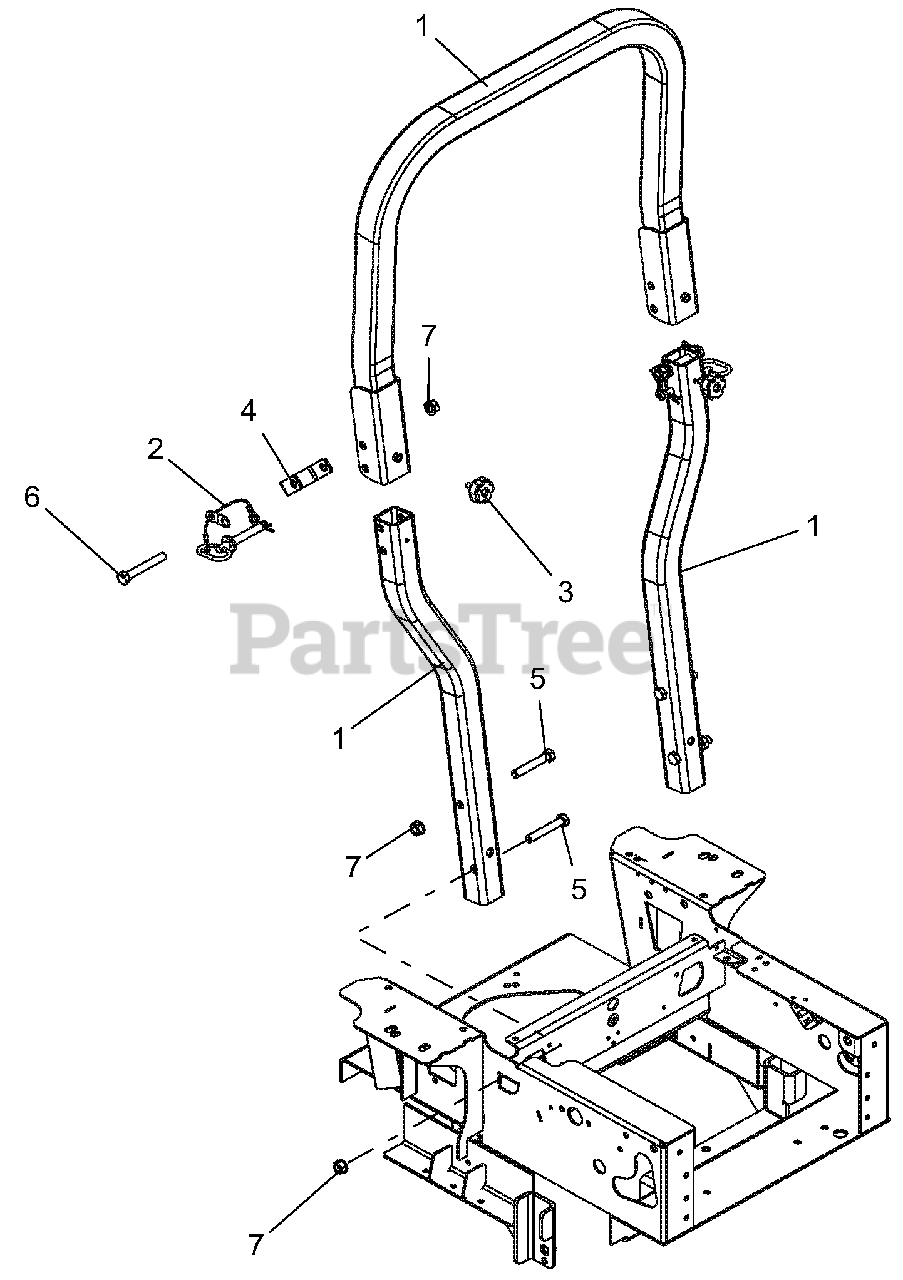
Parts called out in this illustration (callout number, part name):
1	ROPS, PT/PT100 REPLACEMENT
2	ASSY, ROPS PIN/LANYARD
3	KNOB, ROUND 5/16-18 X .750
4	BRKT, ROPS STOP, PRO-TURN YZ
5	BLT-HEX .50-13X3.00 GR5 YWZC
6	BLT-HEX .50-13X3.50 GR5 YWZC
7	NUT, LK-TOP-FLG .50-13 YWZC
